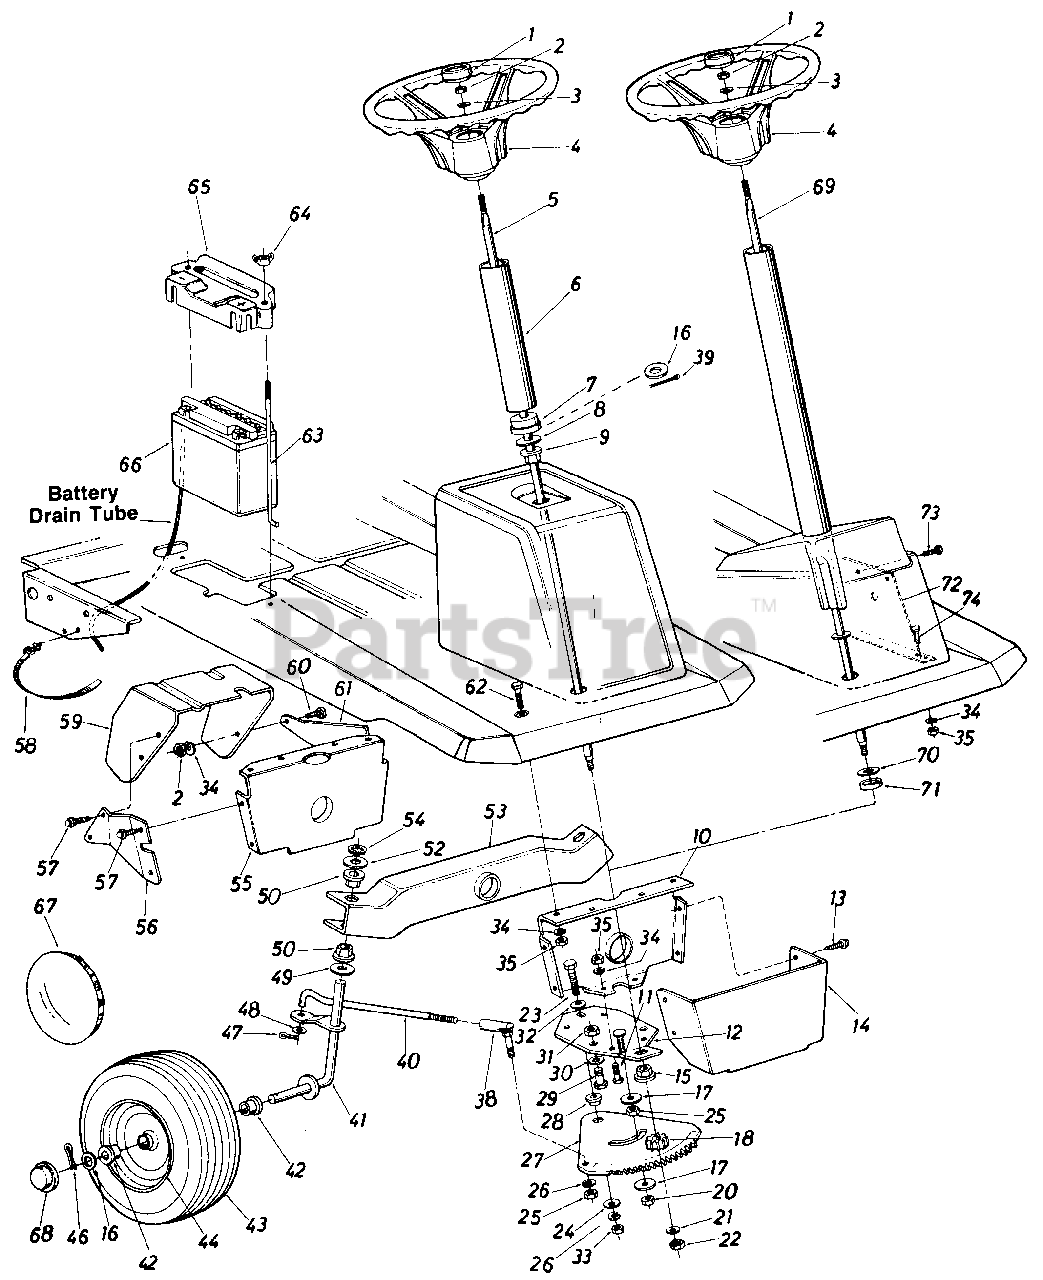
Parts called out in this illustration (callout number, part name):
1	Steering Wheel Cap
2	Hex L-Nut 5/16-24 Thd.
3	Bell-Wash. .345" I.D. x .88" O.D.
4	Steering Wheel Ass'y.
5	Steering Shaft
8	Fl-Wash. .635" I.D. x 1.24 O.D.
9	Hex Flange Bearing
10	Pivot Bar Bracket
11	Hex Bolt 5/16-18 x .75" Lg.
12	Steering Gear Support Brkt.
13	Hex Wash. Hd. AB-Tap Scr. 1/4 x.62" Lg.
16	Fl-Wash. .640" I.D. x 1.5" O.D.
17	Fl-Washer 3/8" I.D. x 1.37" O.D.
18	Steering Pinion Gear
20	Hex L-Nut 3/8-24
21	Fl-Wash. .34" I.D. x .68" O.D.
22	Hex Nut 5/16-24 Thd.*
23	Hex Bolt 3/8-24 x 1.25" Lg.(Grade 5)
24	Fl-Wash. .385" I.D. x 1.38"
25	Hex Nut 3/8-24 Thd.
26	L-Wash. 3/8" I.D.
27	Steering Gear Segment
28	Shoulder Spacer .622" Dia. x .21 8
29	Hex Bolt (Nylon) 1/2-13 x .75"
30	Fl-Wash. .530" I.D. x .930"
31	Hex Nut 1/2-13 Thd.
32	Bell-Wash. .385" I.D. x .88"
33	Hex Nut 3/8-24 Thd.
34	L-Wash. 5/16" I.D.
35	Hex Nut 5/16-18 Thd.
38	Ball Joint Ass'y. 3/8-24 Thd.
39	Cotter Pin 1/8" Dia. x 1.00" Lg.
40	Steering Tie Rod
41	Front Axle Ass'y.-R.H.
42	Flange Bearing .632" I.D.
43	Front Wheel Ass'y. Comp.
44	Front Wheel Rim Only
46	Cotter Pin 1/8" Dia. x 1.25"
47	Cotter Pin 1/8" Dia. x 1.00"
48	Fl-Wash. .385" I.D. x .87"
49	Fl-Wash. .635" I.D. x 1.24"
50	Hex Flange Bearing
52	Fl-Wash. .635" I.D. x 1.12"
53	Pivot Bar Ass'y.
54	Speed Nut 518" I.D.
55	Pivot Bar Bracket
56	Bracket Reinforcement-R.H.
57	Hex Wash. Hd. AB-Tap Scr. 1/4 x.62" Lg.
58	Cable Tie*
59	Clutch-Brake Pedal Ass'y.
60	Hex Bolt 5/16-18 x .75" Lg.
61	Bracket Reinforcement-L.H.
62	Hex Bolt 5/16-18 x .75" Lg.
63	Battery Hold Down Rod
64	Wing Nut Solid 1/4-20 Thd.
65	Battery Hold Down Cover
66	12V Battery
67	Chrome Hub Cap
68	Plastic Hub Cap
69	Steering Shaft Ass'y.
70	Fl-Wash. .635" I.D. x 1.24" O.D.
71	Spacer (Plastic)
74	Hex Bolt 5/16-18 x 2.00" Lg.
